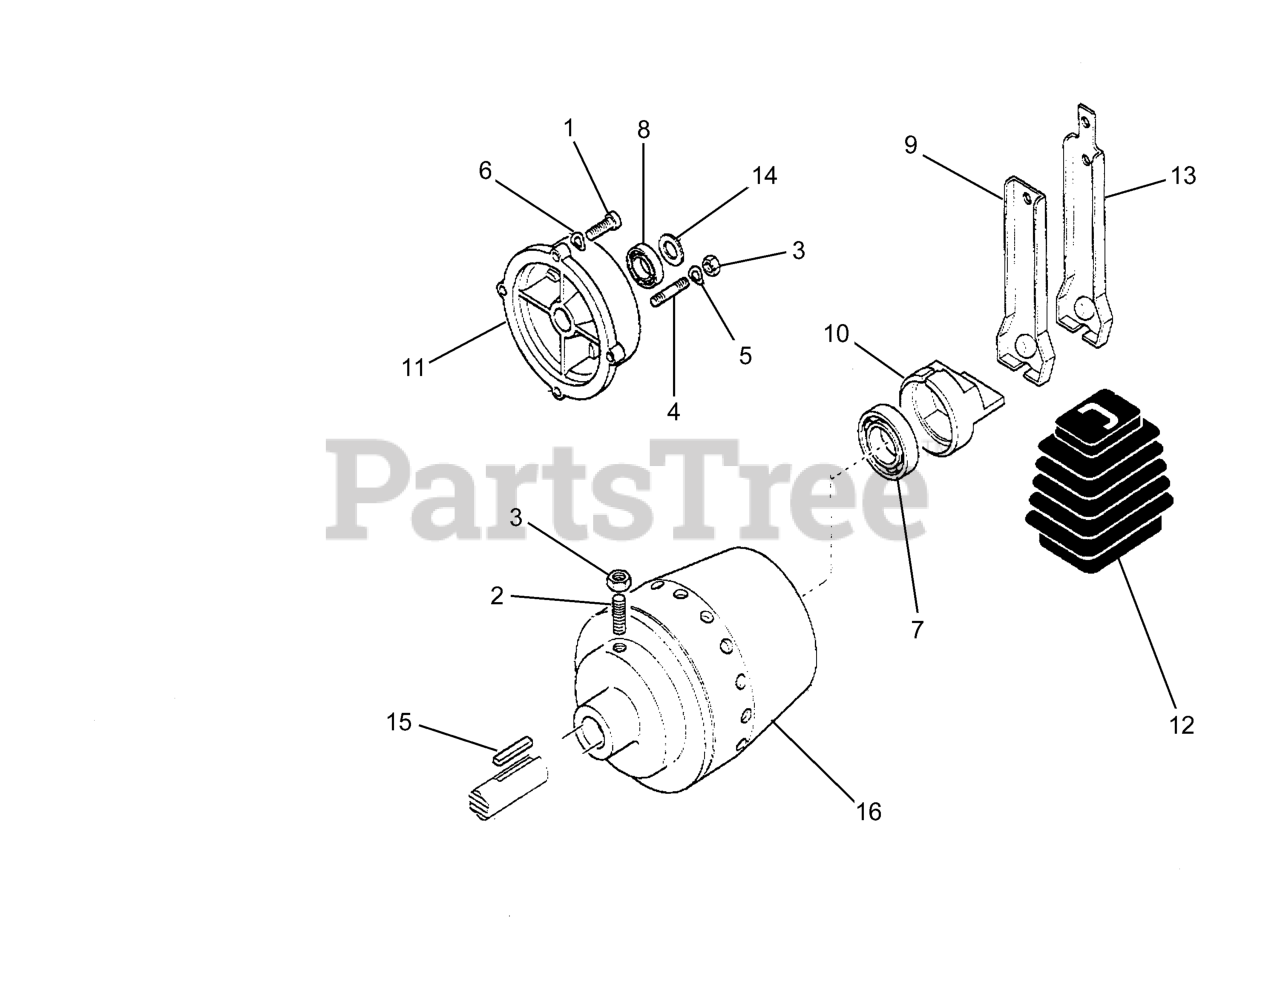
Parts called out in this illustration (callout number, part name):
1	SCREW 3/8X1
2	SCREW M8X30 UNI 5923
3	NUT M8 UNI 5588-5S
4	STUD M8X40X14X14
5	SPRING WASHER B 8.4 DIN 137
6	SPRING WASHER B10,5 DIN 137
7	BEAR.6203 2RS/C3 17X40X12 SKF
8	BEARING 6006 2RS1 SKFC3
9	SHORT CLUTCH LEVER ELEC.START
10	CONE PRESSURE PLATE
11	ENGINE FLANGE B&S 8HP I/P
12	HOOD (FOR CLUTCH LEVER)
13	SELF-COOLING CLUTCH LEVER
14	CLUTCH SHIELD WASHER
15	KOHLER ENGINE KEY
16	CLUTCH D.25.4 1 SPRING
